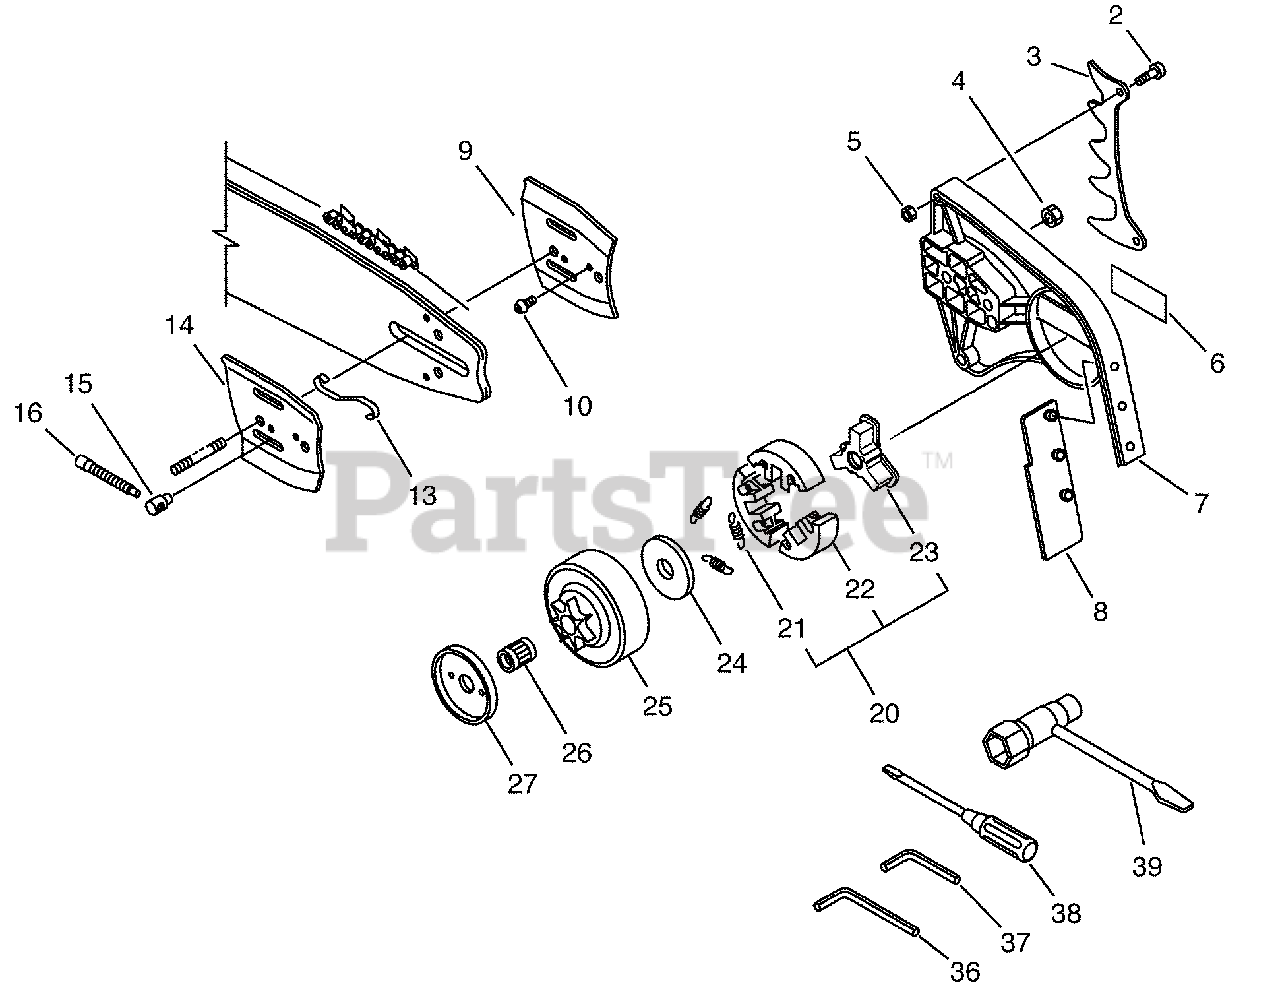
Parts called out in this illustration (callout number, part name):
2	SCREW - 6X20
4	NUT - FLANGE
5	LOCKNUT - 6
6	LABEL - ECHO
7	GUARD, SPROCKET
9	PLATE, GUIDE - OUTER
10	SCREW - 3X6
13	HOLDER, PLATE
14	PLATE, GUIDE - INNER
15	TENSIONER, CHAIN
16	SCREW, TENSIONER
20	CLUTCH ASSY
21	SPRING, CLUTCH
22	CLUTCH SHOE SET
23	HUB, CLUTCH
24	PLATE, CLUTCH
25	DRUM, CLUTCH
26	BEARING, NEEDLE
36	HEX KEY - 5mm
37	HEX KEY - 4mm
38	SCREWDRIVER
39	T-WRENCH - 17X19mm
